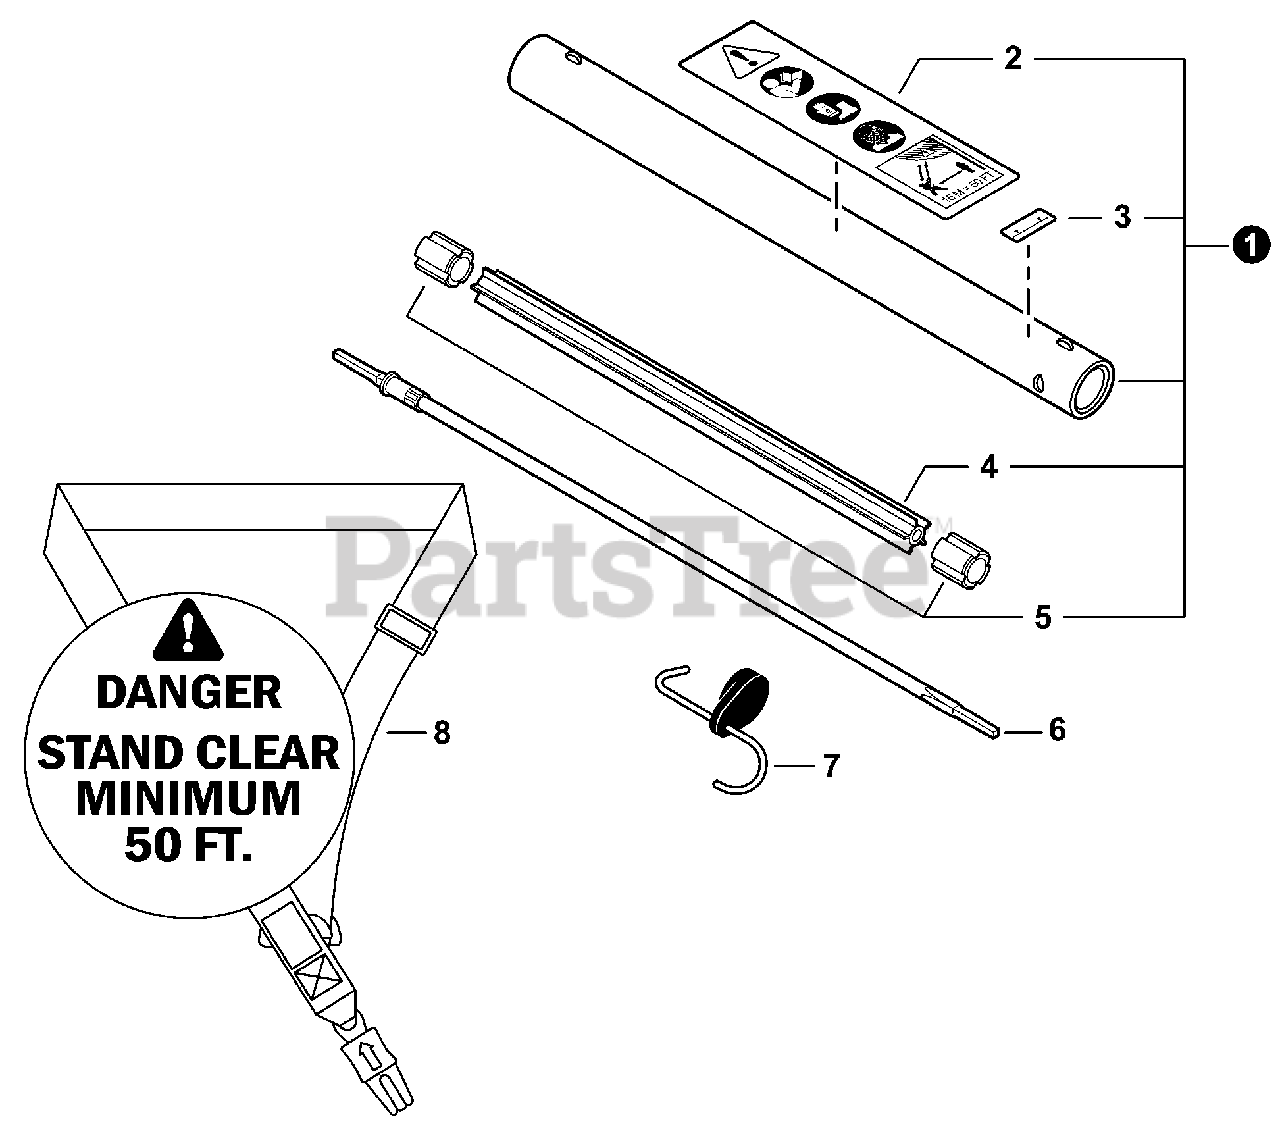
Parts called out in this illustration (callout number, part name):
1	MAIN PIPE ASSY
2	LABEL, CAUTION
3	LABEL - ALIGNMENT
4	LINER - FLEXIBLE
6	DRIVESHAFT - FLEXIBLE
7	HANGER, ATTACHMENT
8	HARNESS, SHOULDER
